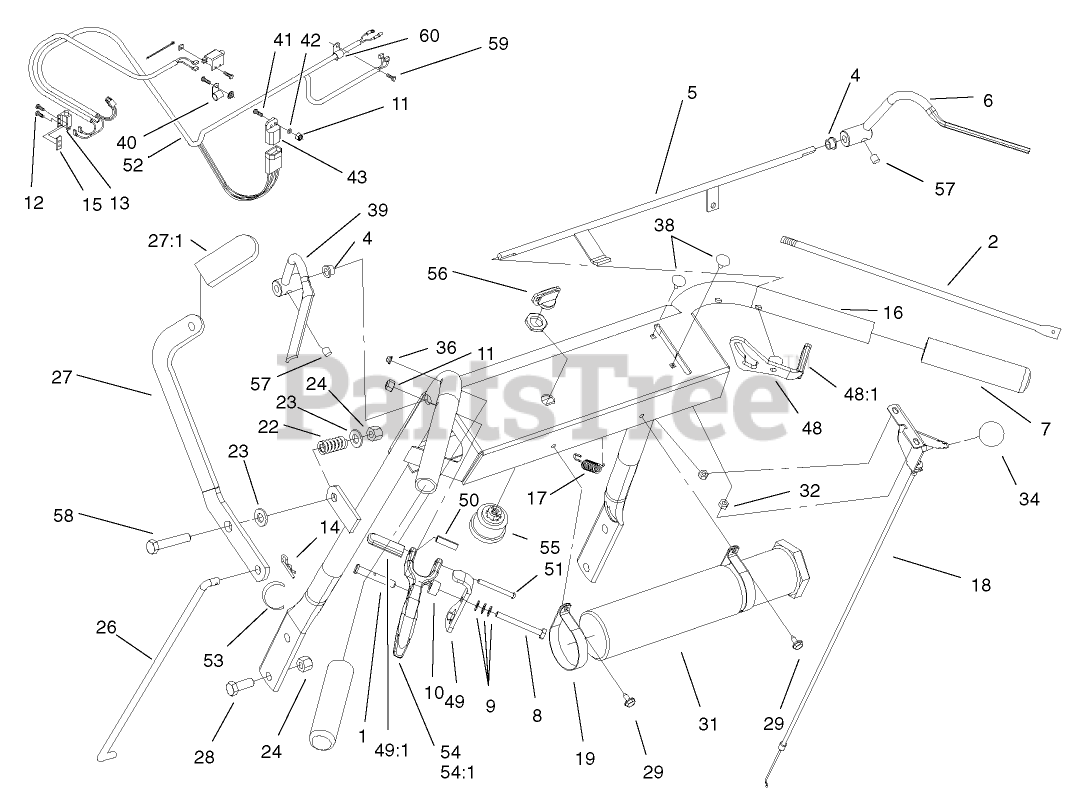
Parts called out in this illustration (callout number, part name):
1	PIN-CLEVIS
2	Linkage-Wheel, Drive
4	BUSHING-NYLON
5	ROD-CONTROL, OPERATOR PRESENCE
6	LEVER-RH
7	Grip-Handle
8	SCREW-HH
9	WASHER-SPRING
10	SPACER
11	NUT-LOCK, NI
12	SCREW-PPH
13	SWITCH-OPEN, NORMALLY
14	PIN-COTTER
15	PLATE-TAPPED
16	HANDLE ASM
17	SPRING-EXTENSION
18	THROTTLE CABLE ASM
19	CLAMP-R
22	SPRING-COMPRESSION
23	WASHER-FLAT
24	NUT-LOCK, NI
26	Linkage-Blade, Upper
27	LEVER ASM
27:1	GRIP-LEVER
28	SCREW-HH
29	SCREW-HWHTF
31	TUBE-MANUAL
32	NUT-LOCK, NI
34	KNOB-BALL
38	BOLT-CARR
39	LEVER-LH
40	CLIP-LOOM
41	SCREW-HH
42	WASHER-FLAT
43	MODULE-INTERLOCK
48	RH THUMB LATCH ASM
48:1	GRIP-LATCH
49	LH THUMB LATCH ASM
49:1	GRIP-LATCH
50	PIN-ROLL
51	PIN-LEVER, DRIVE
52	HARNESS-WIRING
53	Clip-Cable
54	Drive Lever ASM
54:1	GRIP-LEVER, DRIVE
55	SWITCH & KEY (INCLUDES NUT & WASHER)
56	KEY-IGNITION
57	SCREW-SET
58	SCREW-HH
59	SCREW-HH
60	Clip-Loom
